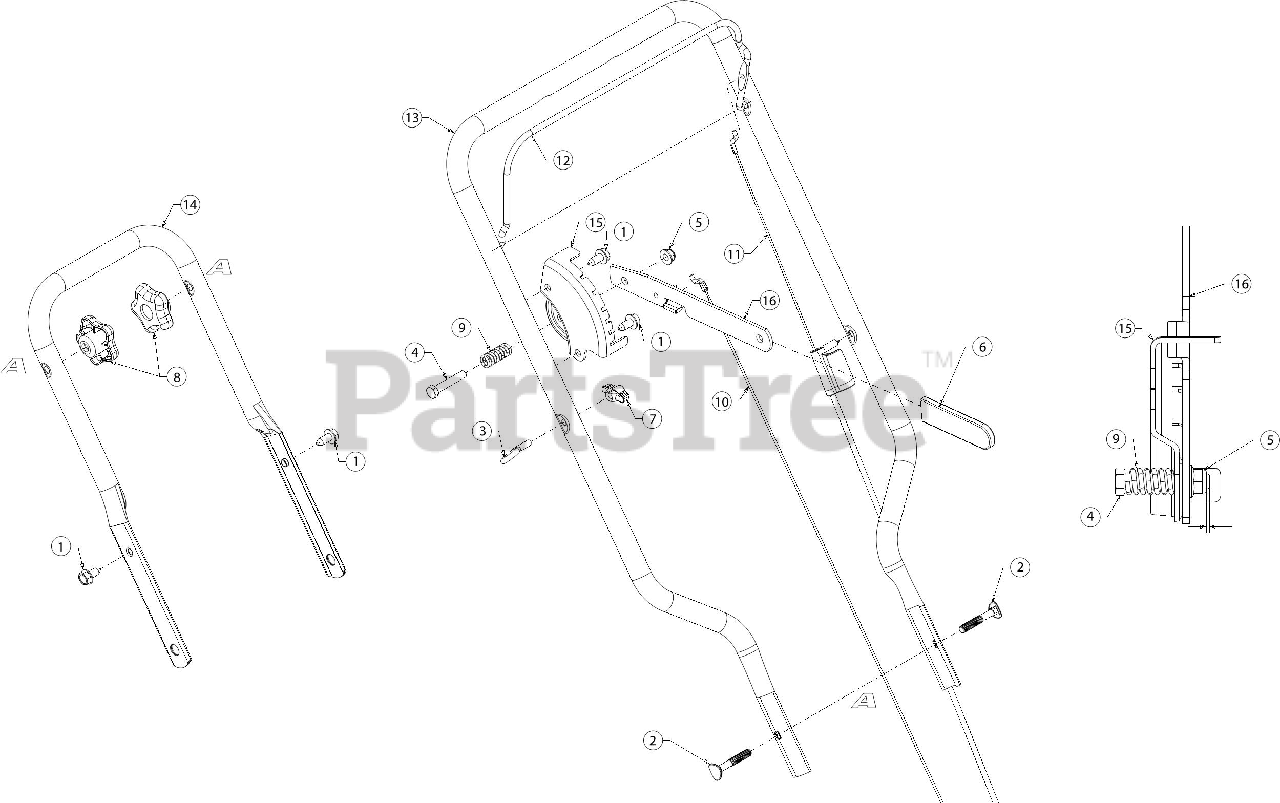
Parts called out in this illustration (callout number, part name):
1	SCREW 5/16-12 x .750
2	SCREW 5/16-18 x 2.0
3	EYEBOLT 1/4-20
4	SCREW 5/16-18 x 1.75 GR5
5	FLANGE LOCK NUT 5/16-18
7	HANDLE KNOB
8	STAR KNOB 5/16-18
9	SPRING
10	WHEEL ADJUSTMENT CABLE
11	CONTROL CABLE 31"
12	BLADE CONTROL BAIL
16	LEVER DEPTH
